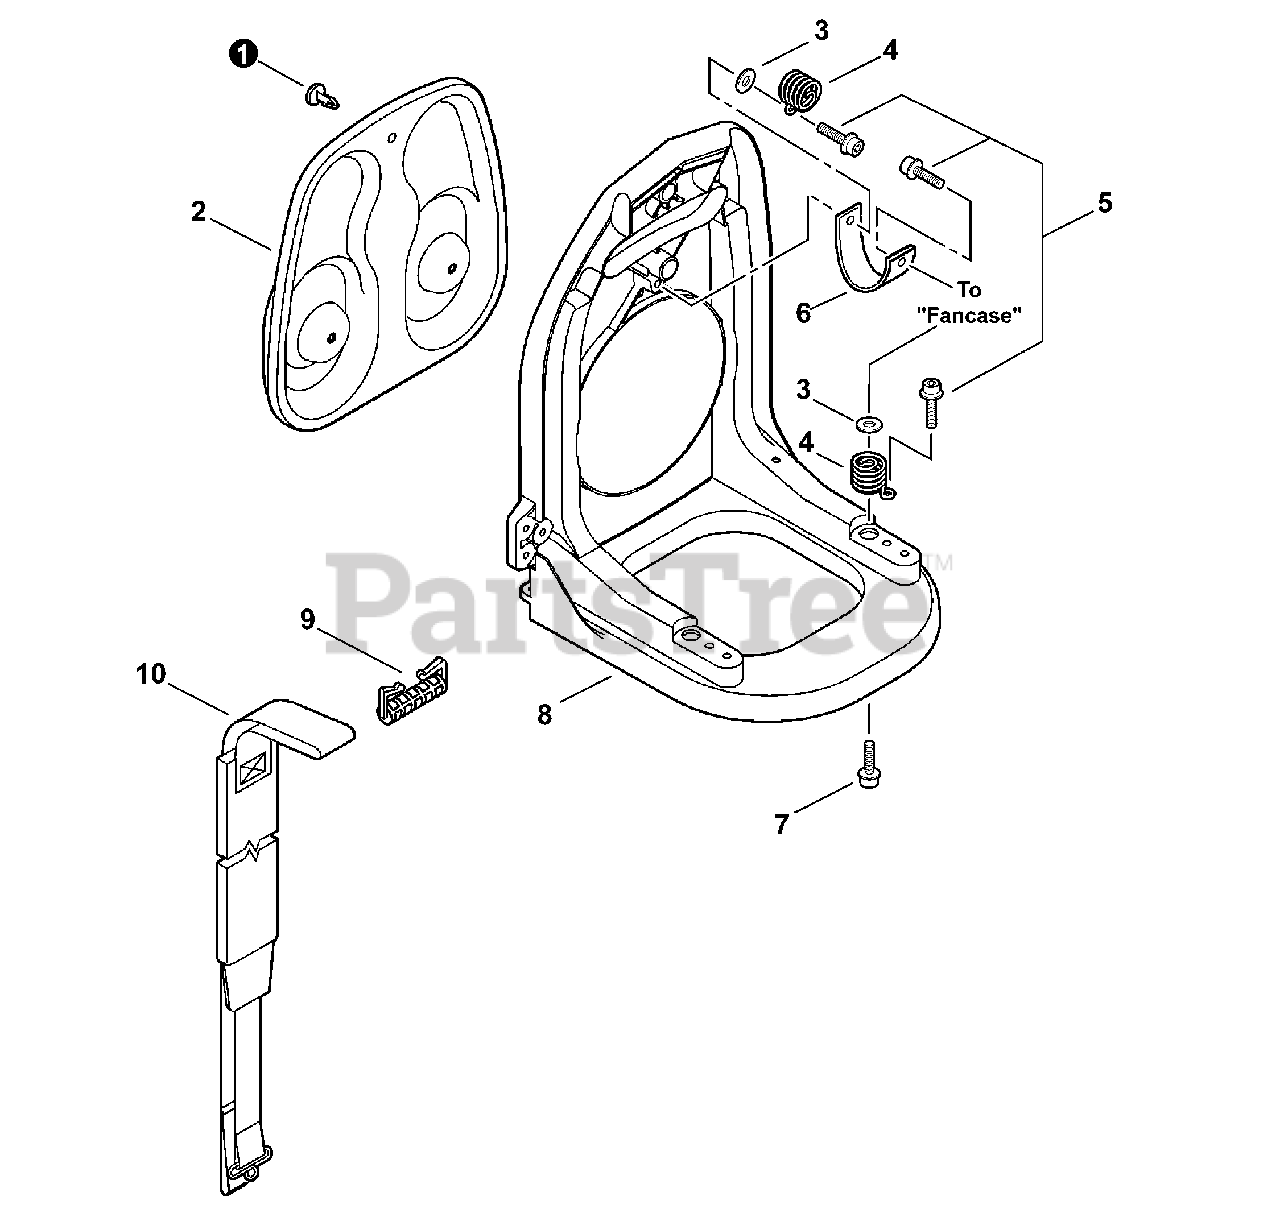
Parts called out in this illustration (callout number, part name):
2	CUSHION, BACKPACK
3	WASHER 5.5×16×2T
4	SPRING, COMPRESSION
5	BOLT 5×20
6	STRAP, SAFETY 1.2×100
7	BOLT 5×14
8	FRAME, BACKPACK
9	CLIP, HARNESS
10	HARNESS ASSY, BACKPACK
